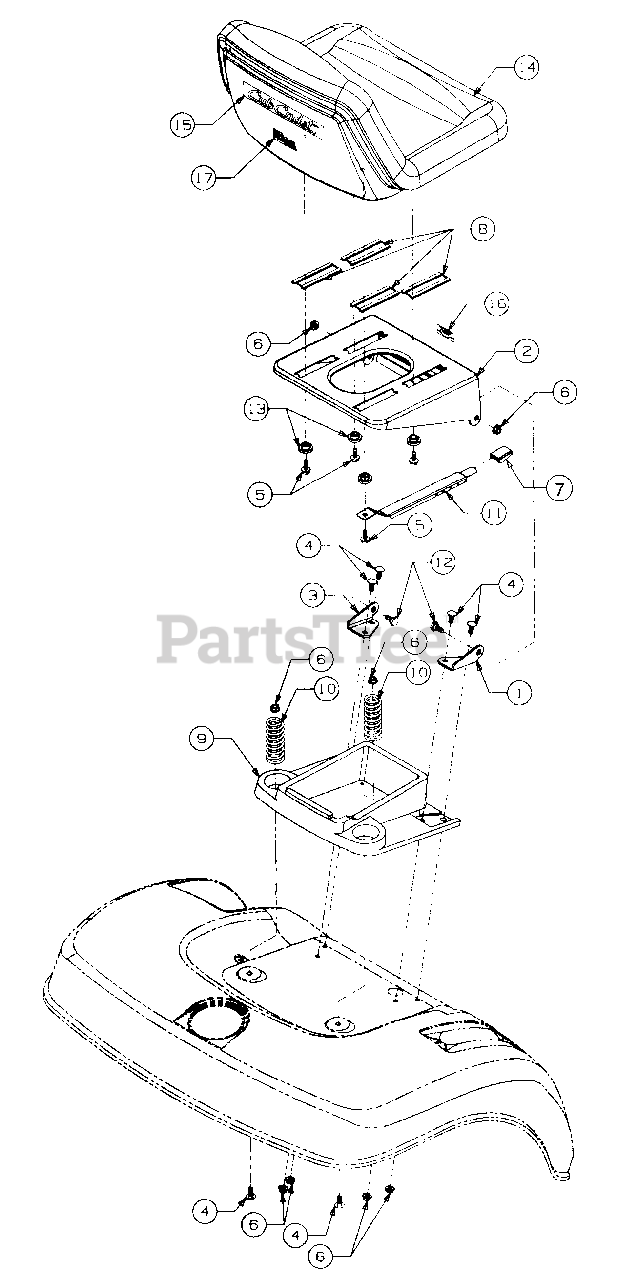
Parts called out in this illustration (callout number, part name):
1	Bracket, RH Seat Pivot
2	Seat, Base
3	Bracket, LH Seat Pivot
4	Bolt, Carriage, 5/16-18 x .75
5	Screw, Hx Wsh Hd Tap 5/16-18 x .75
6	Nut, Hex Flange Lock, 5/16-18
7	Knob, Seat Adjuster
8	Slide, Seat
9	Tray, Tool
10	Spring, Comp, 1.9 OD x 2.4 Lg
11	Adjuster, Seat
12	Bolt, Shoulder
13	Spacer, Shoulder
14	Seat, High Back
15	Graphic, Seat Back Script
16	Graphic, Seat Adjuster
17	Graphic, Made in USA
